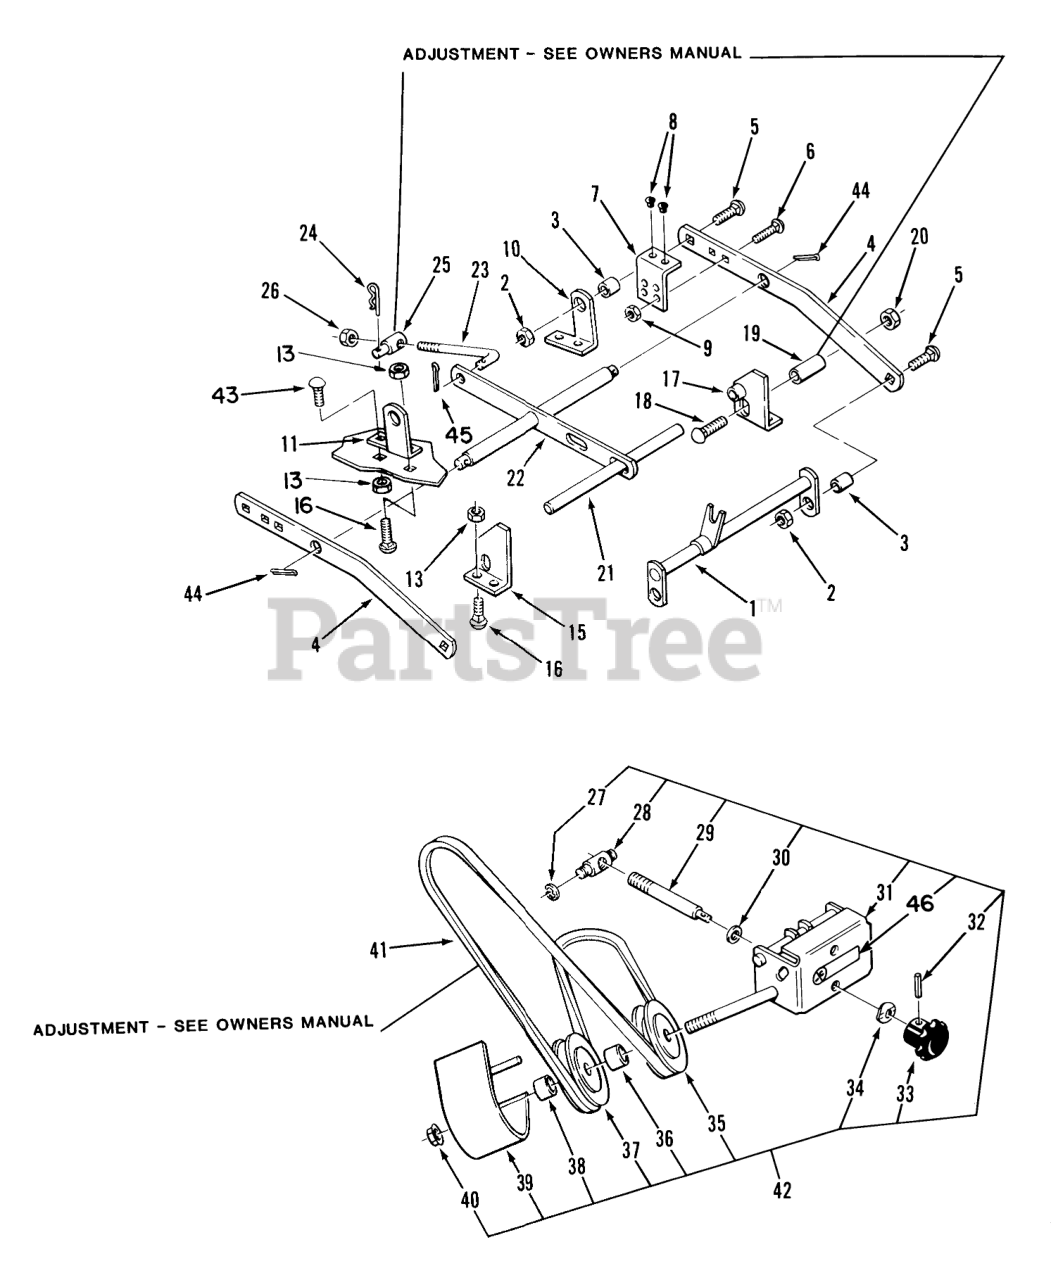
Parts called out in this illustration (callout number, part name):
1	Hitch
2	LOCKNUT-FLANGE
3	SPACER
4	Bar Draft
5	BOLT-CARR
6	BOLT-CARR
7	Bumper-Metal
8	BUMPER-RUBBER
9	Nut
10	LH Rear Bracket
11	Rear Bracket RH
13	NUT-HEX
15	Front Bracket RH
16	SCREW-CARR
17	Front Bracket LH
18	BOLT-CARR
20	Nut
21	Front Shaft
22	Leveler
23	ROD-LEVEL ADJUST
24	Hairpin
25	TRUNNION-LIFT
26	NUT-LOCK, NI
27	RING-RETAINING
28	TRUNNION-DOUBLE
29	ROD ADJ
30	Washer
31	Front Support
32	PIN-ROLL
33	KNOB-ADJUSTMENT
34	WASHER-SPRING
35	Pulley-V
36	SPACER
37	PULLEY-FLAT IDLER
38	SPACER-OUTER
39	Belt Cover
40	Nut
41	V-BELT
42	ASM-SUPPORT,IDLER
43	Bolt
44	Cotter Pin
45	PIN-COTTER
46	Decal-Attac-O-Matic
